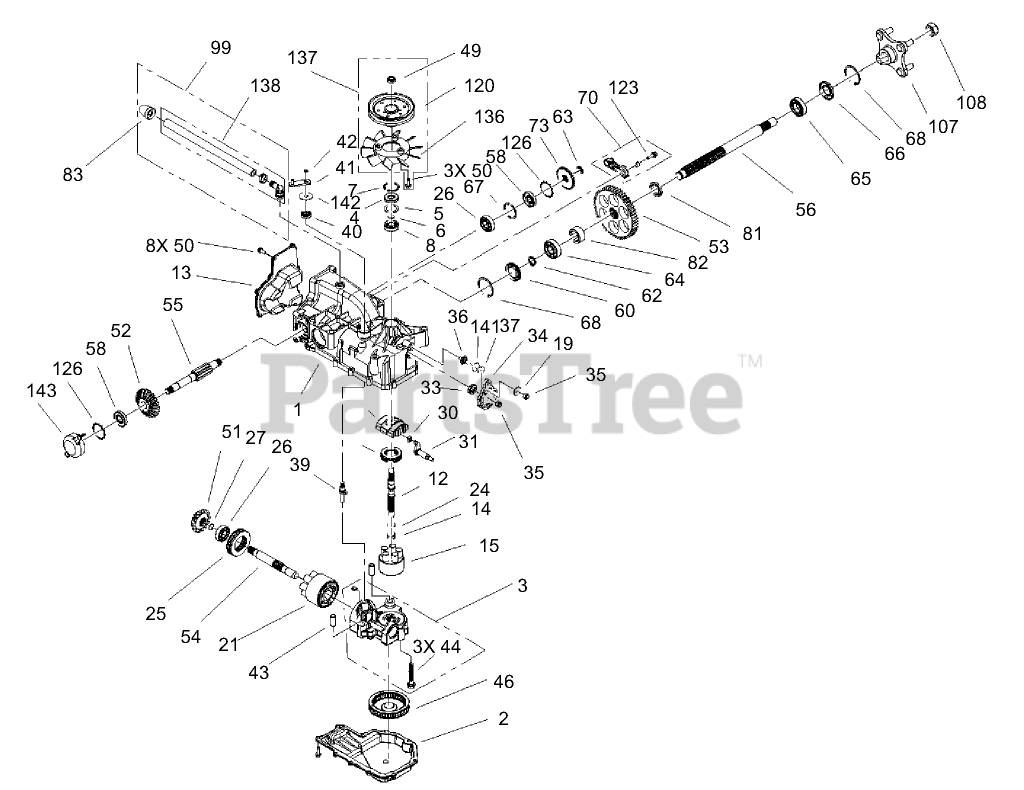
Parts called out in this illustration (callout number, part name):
1	MAIN HOUSING KIT
2	HOUSING-LOWER
3	CENTER SECTION KIT ASM
4	SEAL-LIP
5	SPACER
6	RING-WIRE, RETAINING
7	RING-RETAINING
8	BEARING-SHAFT, BALL
10	SWASHPLATE-VARIABLE
11	BEARING-THRUST
12	SHAFT-INPUT
13	COVER-BACK
14	SPRING-BLOCK
19	WASHER-PIVOT
24	WASHER-THRUST
25	BEARING-THRUST
26	BEARING-BALL
27	RING-RETAINING
30	GUIDE-SLOT
31	TRUNNION ASM
33	SEAL-LIP
34	ARM-CONTROL
37	PUCK-FRICTION
38	PLATE-BYPASS
39	ACTUATOR-BYPASS
40	SEAL-LIP
41	ARM-BYPASS
42	RING-RETAINING
46	FILTER
49	NUT-LOCK
51	GEAR-BEVEL, 14T
52	GEAR-BEVEL, 19T
53	GEAR-BEVEL, 53T
54	SHAFT-MOTOR
55	SHAFT-BRAKE
56	SHAFT-AXLE
58	SEAL-LIP
60	PLUG-SIDE SEAL
62	RING-AXLE, RETAINING
63	RING-RETAINING
64	BEARING-BALL
65	BEARING-BALL
67	RING-RETAINING
68	RING-RETAINING, AXLE
70	LH BRAKE ARM ASM
73	DISC-BRAKE
81	BUSHING-AXLE
83	CAP VENT ASM
99	BREATHER KIT
107	HUB ASM
120	PULLEY
123	SCREW-HHF
126	RING-RETAINING
138	HOSE/FITTING ASM
141	WASHER
142	WASHER
143	COVER-BRAKE, PLASTIC
